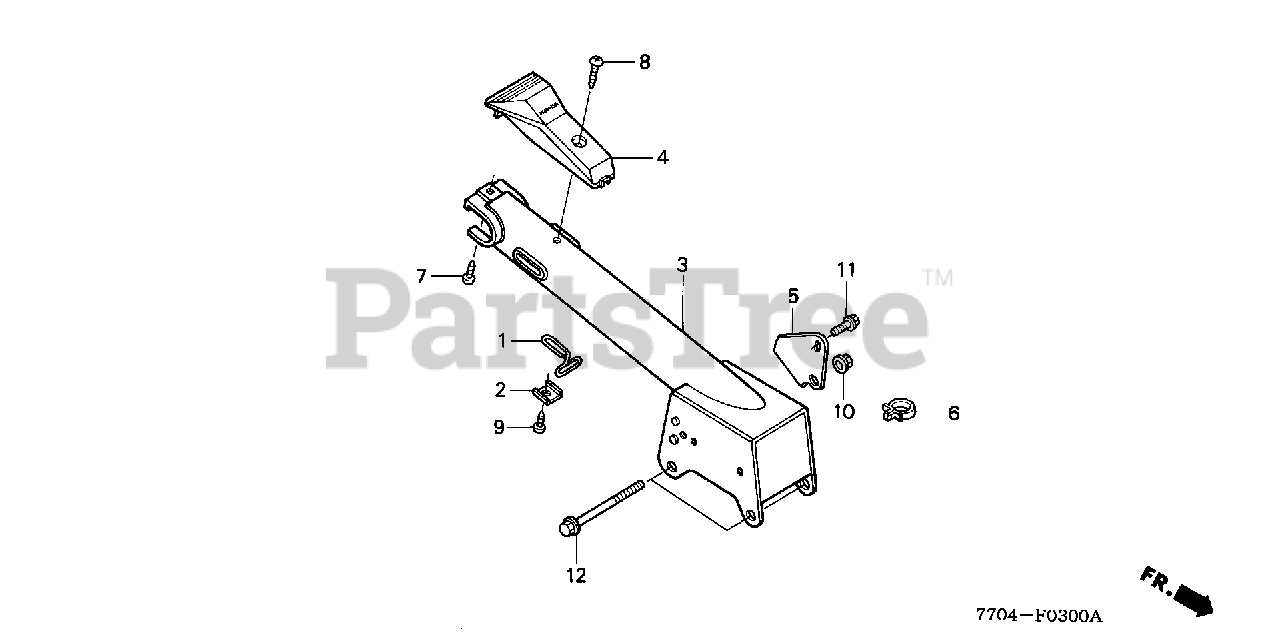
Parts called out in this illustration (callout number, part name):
1	GUIDE, CABLE
3	COLUMN, HANDLE *R280* (POWER RED)
4	COVER, HANDLE *NH278* (QUARTER GRAY)
5	BRACKET, REVERSE STOP BAR
6	CLIP, WIRE HARNESS
7	SCREW, TAPPING (5X16)
8	SCREW, TAPPING (5X25)
9	SCREW, TAPPING (5X10)
10	NUT, FLANGE (10MM)
11	BOLT, FLANGE (6X16)
12	BOLT, FLANGE (10X110)
